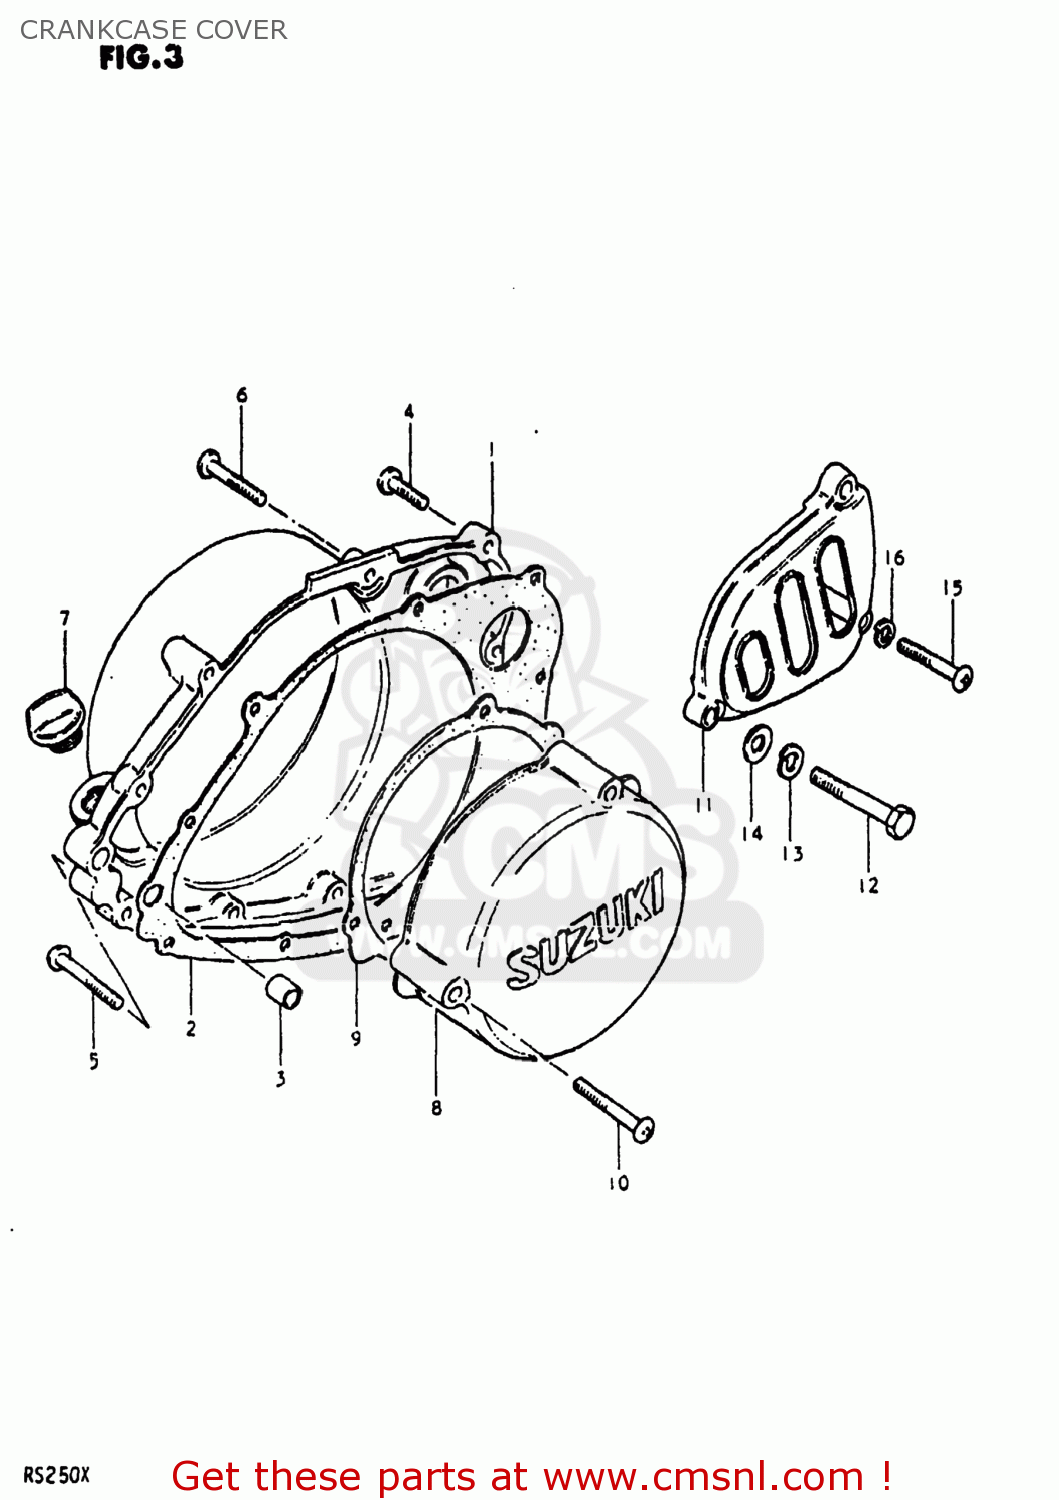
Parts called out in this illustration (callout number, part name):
1	COVER,CLUTCH
2	GASKET,CLUTCH COVER (MCA)
3	PIN
4	SCREW
5	SCREW (6X45)
6	SCREW 6X30
7	PLUG,OIL FILTER
8	COVER,MAGNETO
9	GASKET,MAGNETO COVER (NAS)
10	SCREW
11	COVER,ENGINE SPROCKET
12	BOLT 8X55
13	LOCK WASHER
14	WASHER
15	SCREW
16	LOCK WASHER
